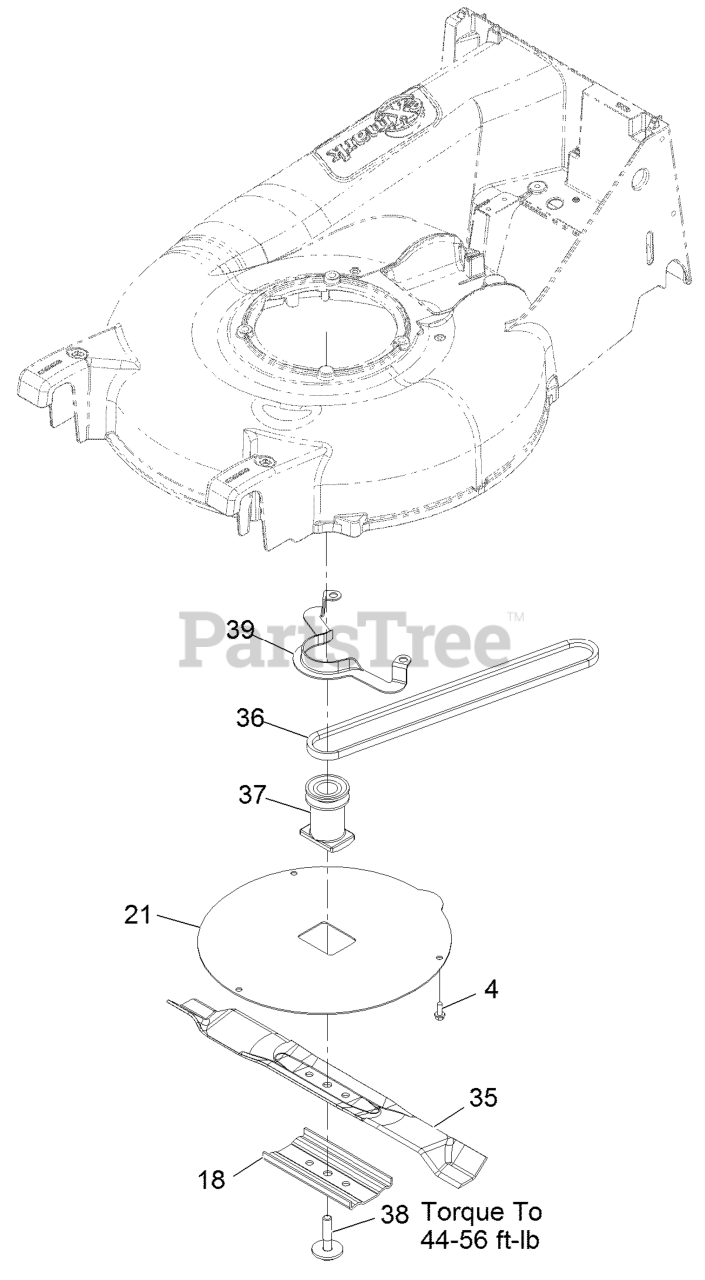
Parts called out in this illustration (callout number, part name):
4	SCREW-HWH
18	SUPPORT-BLADE
35	Blade - Medium Lift, 20.5
36	BELT,3L P21 DRIVE
37	BLADE-ADAPTER
38	BOLT-BLADE, SEM
39	GUIDE-BELT
